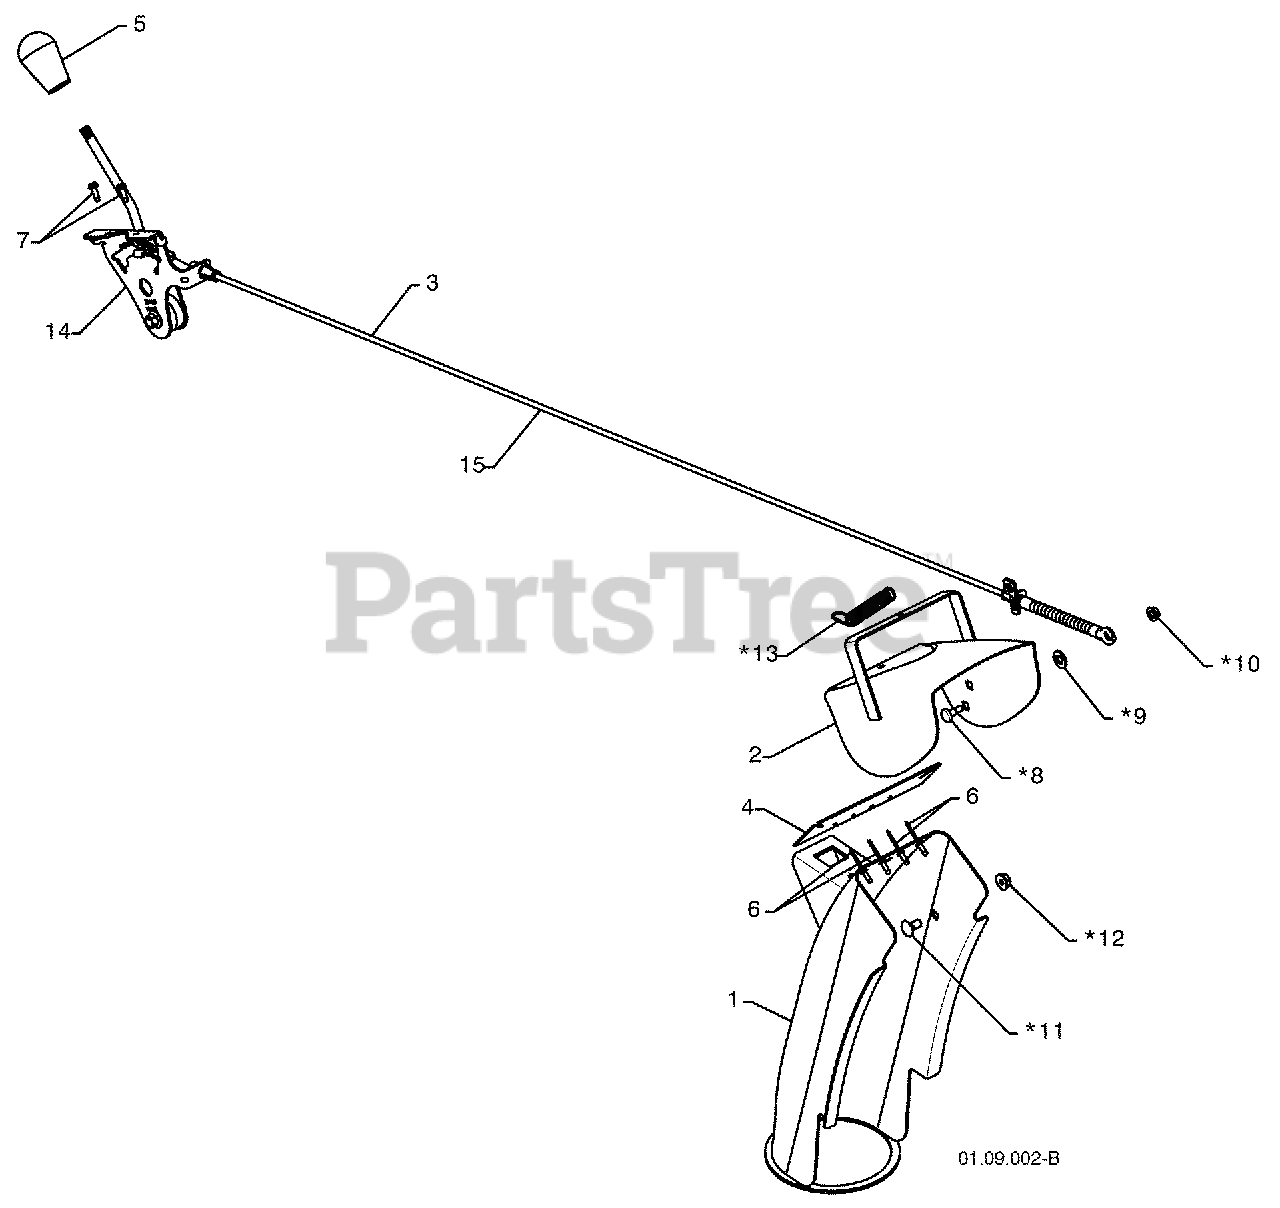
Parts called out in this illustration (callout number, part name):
1	CHUTE WELDMENT
2	DEFLECTOR WELDMENT
3	DEFLECTOR CONTROL ASSEMBLY
4	DEFLECTOR SEAL
5	KNOB BLACK
7	SCREW 10-24 X .625
8	SHOULDER SCREW
9	PLASTIC WASHER
10	NUT 1/4-20
11	CARRIAGE BOLT 5/16-18 X .50
12	NUT 5/16-18
13	DEFLECTOR SPRING
14	(SERVICE PART) DEFLECTOR CONTROL HEAD
15	(SERVICE PART) DEFLECTOR CONTROL CABLE
